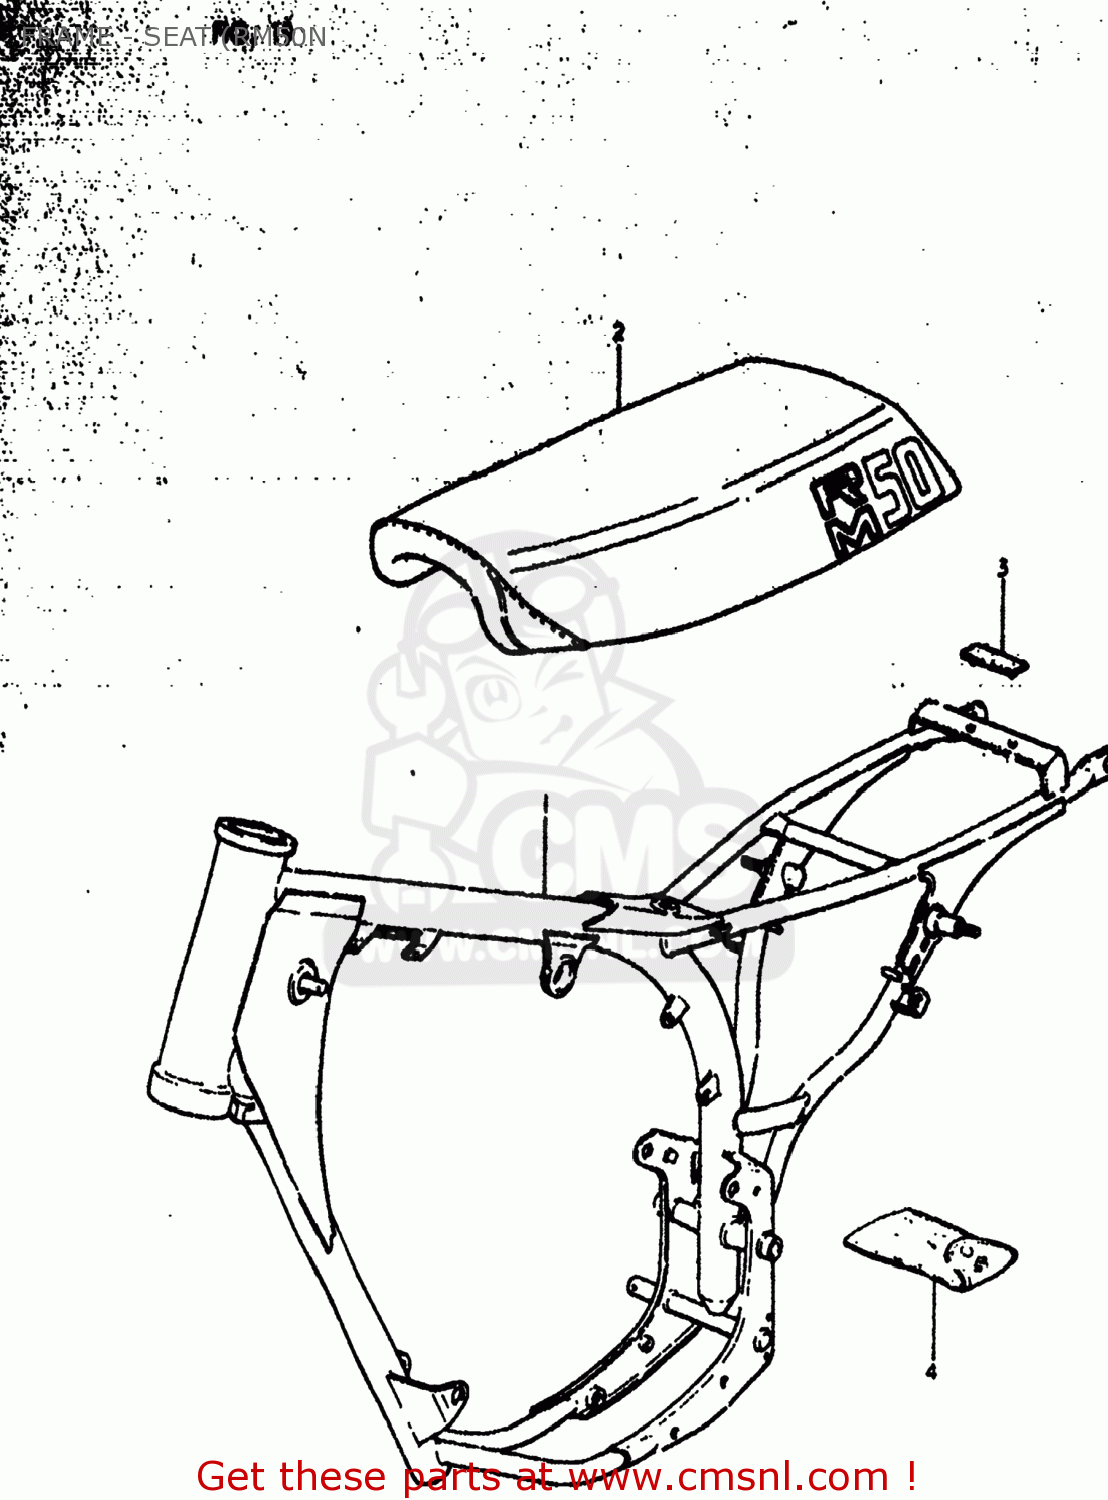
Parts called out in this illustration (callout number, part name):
1	FRAME
2	SEAT ASSEMBLY
3	CUSHION
4	TOOL SET
